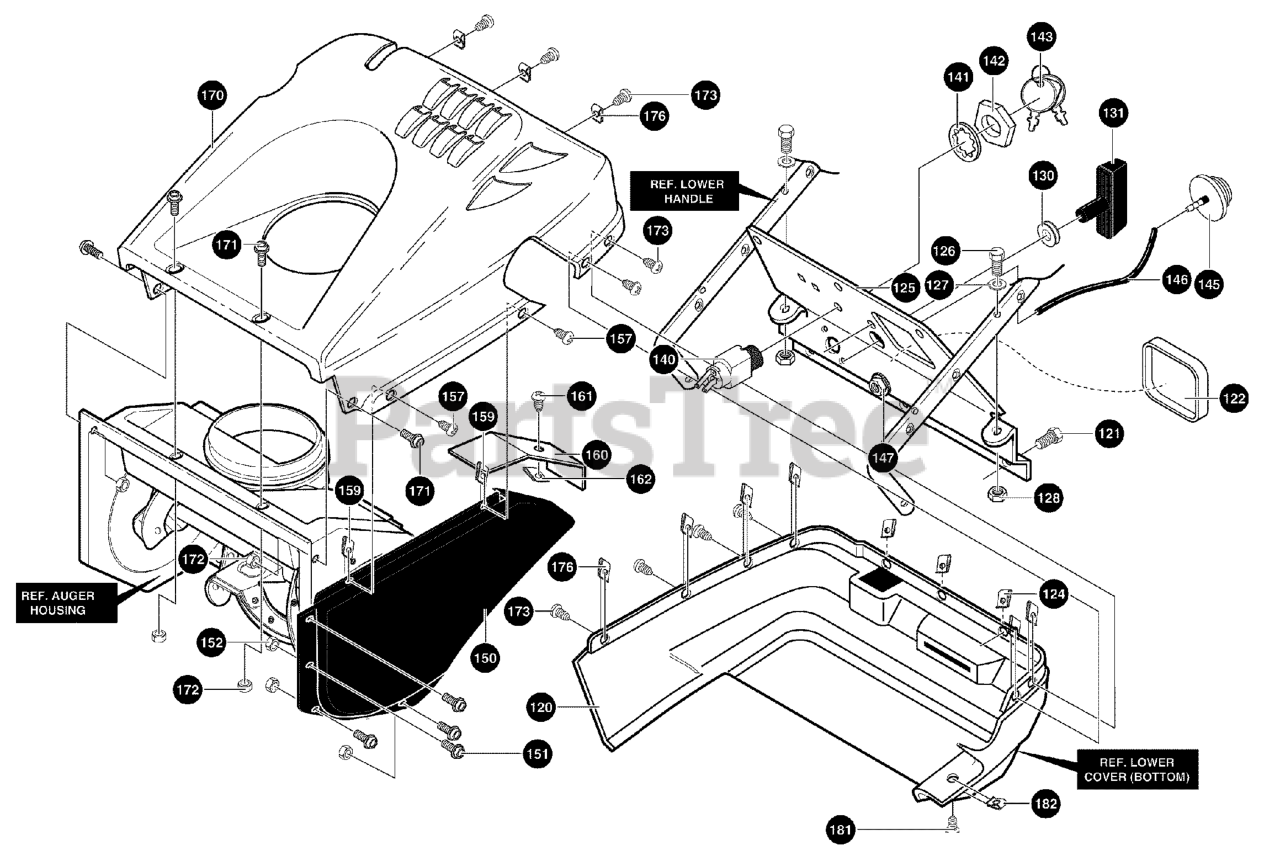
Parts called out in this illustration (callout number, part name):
120	COVER, BOTTOM
121	SCREW, 1/4-14X.75
122	PANEL, SPARK ACCESS
124	NUT, 1/4-10 SPEED J TYPE
125	CONTROL PANEL
126	SCREW, 1/4-20X1.25
127	FLATWASHER
128	NUT, 1/4-20
130	GOMMET & WASHER
131	KNOB T
140	SWITCH, IGNIT.
141	WASHER
142	NUT. 5/8-32
143	KEYS & RING
145	PRIMER, BULB
146	HOSE PRIM 9.50LG
147	NUT, 1/4-20
150	COVER, BELT
151	SCREW, 10-24X.50
152	NUT, #10-24
157	SCREW, 1/4-14X.75
159	NUT, 1/4-10 SPEED J TYPE
160	SHIELD, HEAT
170	COVER, TOP
171	SCREW,#10-24X.50
172	NUT #10-24
173	SCREW, 1/4-14X.75
176	NUT, 1/4-10 SPEED J TYPE
181	SCREW, 1/4-14X.75
182	NUT 1/4-10 SPEED J TYPE
